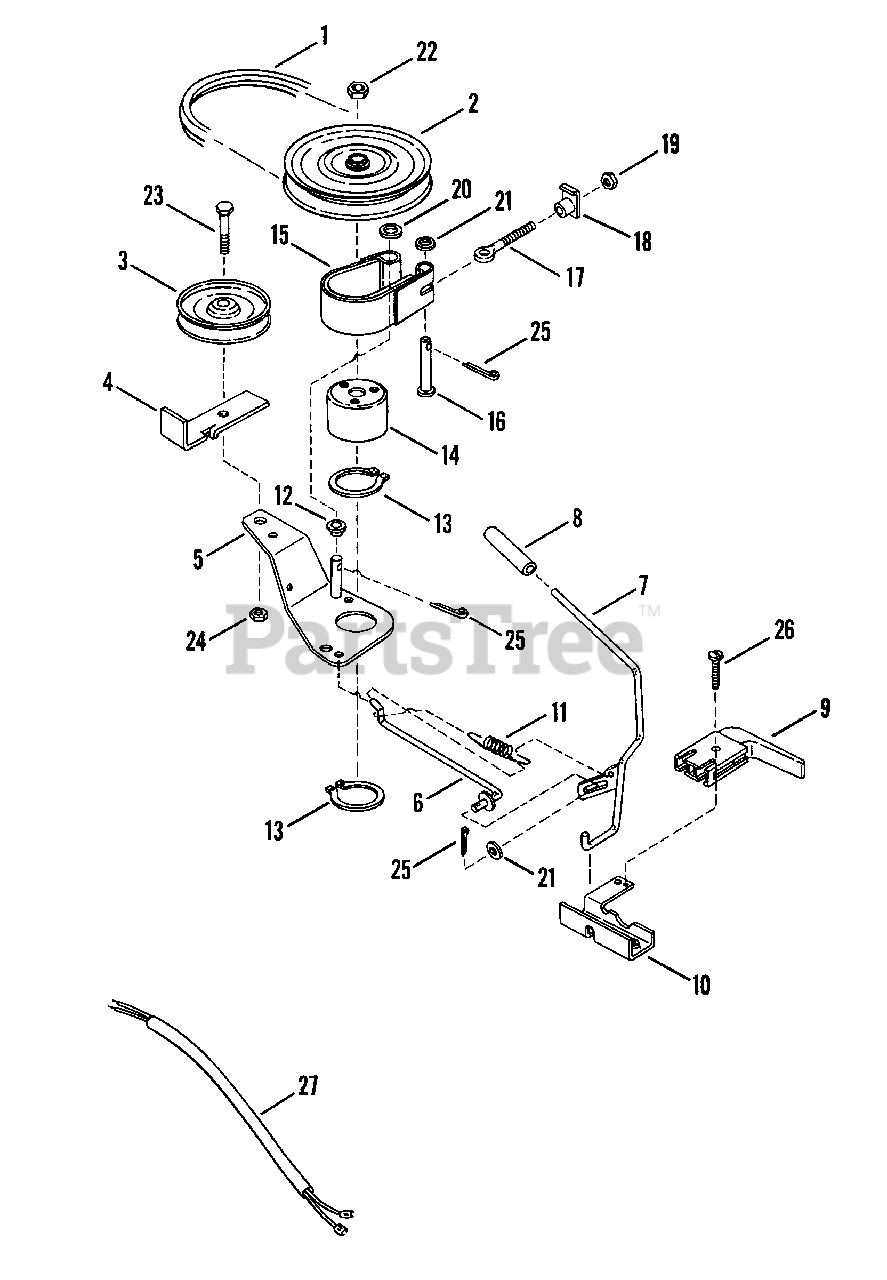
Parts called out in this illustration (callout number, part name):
1	BELT, Drive -25, 26, 28, 30" Models
2	PULLEY, Spindle (Note: Also use 15290)
3	PULLEY, Idler
4	RESTRICTOR, Belt
5	ARM, Idler
6	ROD, Idler
7	HANDLE, Blade ON - OFF (Lever)
8	GRIP, Handle
9	SWITCH, Deck Interlock
10	MOUNT, Handle
11	SPRING, Blade Handle
12	SPACER
13	RING, 2" External Retaining
14	DRUM, Brake
15	BAND, Brake Assembly
16	PIN, 1/4 Clevis
17	EYE-BOLT
18	TEE-NUT
19	NUT, 1/4 Hex
20	WASHER, 3/8 SAE
21	WASHER, 1/4 SAE
22	NUT, 3/4-16 Hex Jam
23	CAPSCREW, 3/8-24x1 3/4" Hex Head
24	LOCKNUT, 3/8-24
25	COTTER-PIN, 3/32x3/4"
26	SCREW, #10X1" Self-Tapping
27	HARNESS, Deck Interlock Wiring
